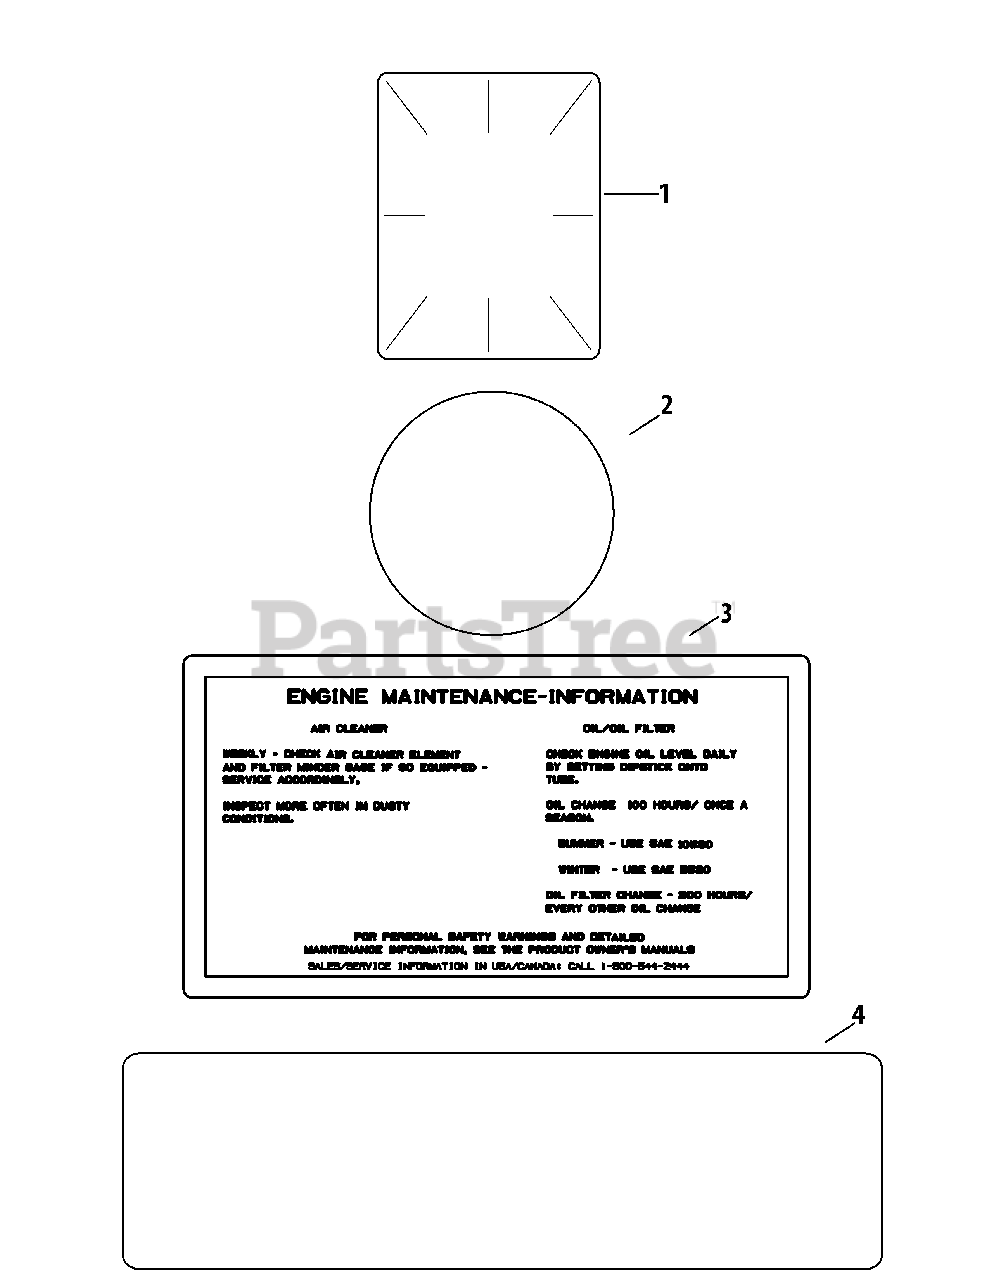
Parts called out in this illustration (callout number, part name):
1	Clear Laminate Decal
2	Grass Screen Decal
3	Air Cleaner Decal
